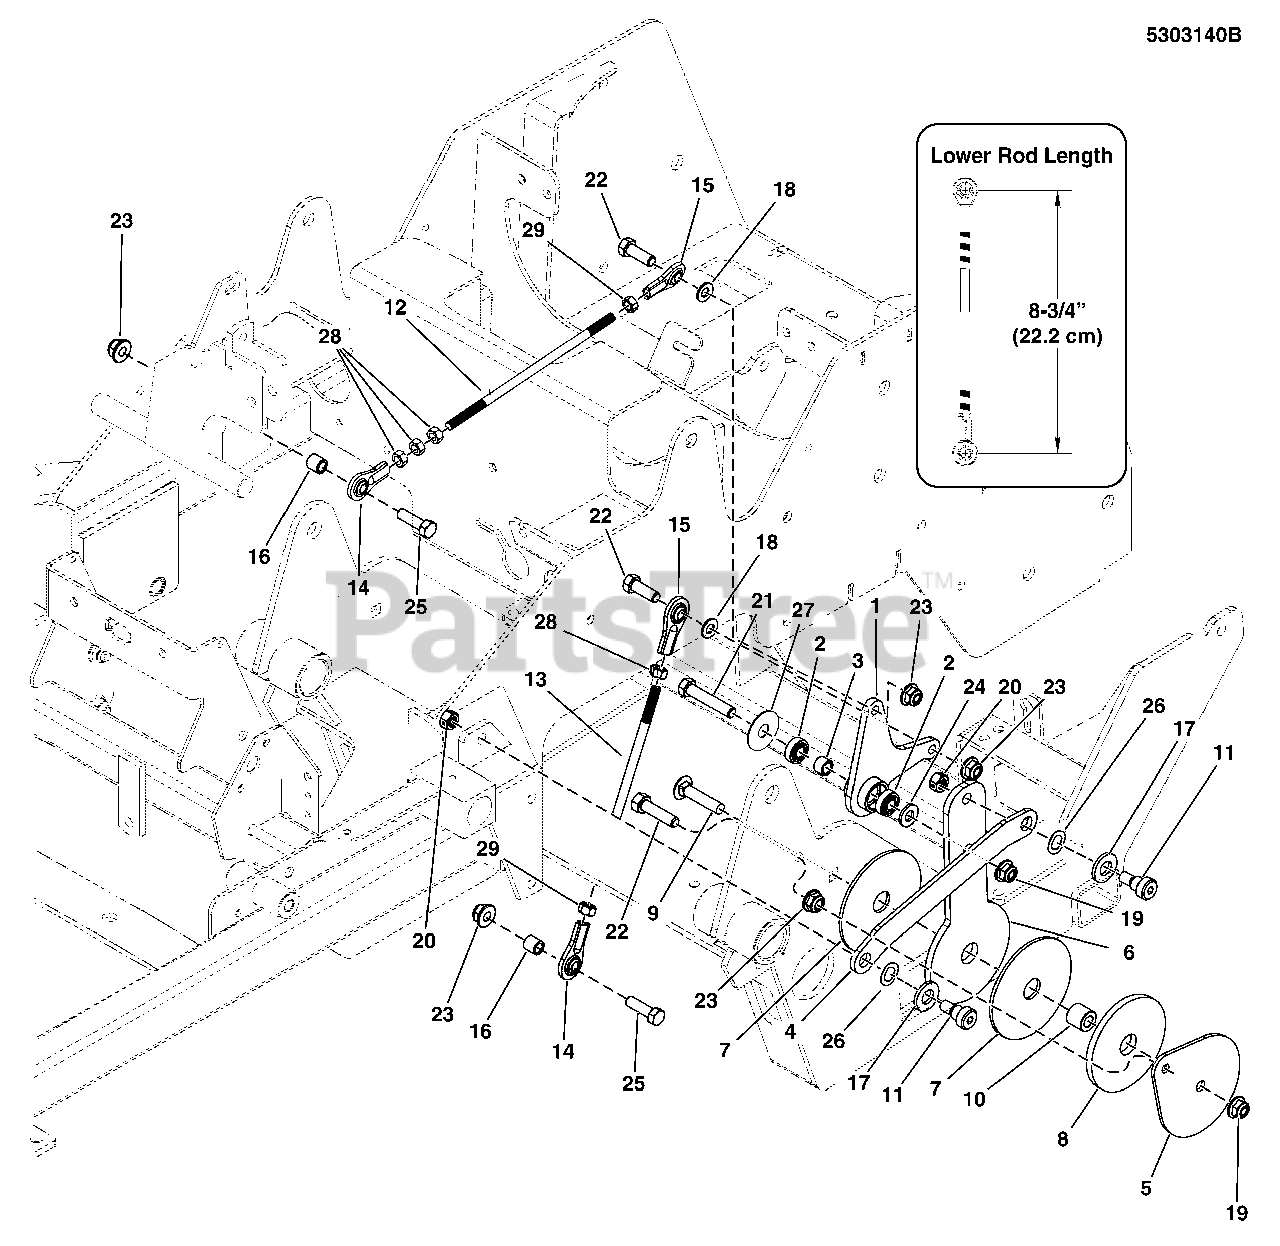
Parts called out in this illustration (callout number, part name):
1	PIVOT, CONTROL SYSTEM, S125XT
2	BEARING, .375" ID X .875" OD X .341" THK
3	SPACER, .39 X .55 X .38, PM, CZ
4	LINK, CONTROL SYSTEM ARM, IS600 - BLK
5	PLATE, CONTROL SYSTEM LOCK - BLK
6	PLATE, CONTROL SYSTEM ARM - HT
7	PAD, CONTROL SYSTEM
8	PAD, .77 X 3.50 X .25, POLYURETHANE
9	BOLT, 3/8-16 X 1-1/2, CARRIAGE, GD5, CZ
10	SPACER, .39 X .75 X .69, PM, CZ
11	BOLT, 3/8-16 X 3/8", 1/2" SHOULDER
12	ROD, 5/16 X 8.38, LH-RH, CZ
13	ROD, 5/16 X 7.00, LH-RH, CZ
14	BALL JOINT 5/16-24 RH FEMALE STAMPED STL
15	BALL JOINT 5/16-24 LH FEMALE STAMPED STL
16	SPACER, .33 X .50 X .50, YZ
17	WASHER, 1/2" GD9 YZ
18	WASHER, 5/16" SAE
19	NUT, 3/8 - 16 HEX NYLOCK FLANGE
20	NUT, Hex, Side Lock, 3/8-16
21	BOLT, 3/8-16 X 2, GD5, CZ
22	BOLT, 5/16-18 X 1-1/4" GD5 YZ
23	NUT, 5/16-18 HEX NYLOCK FLANGE NUT
24	WASHER, 3/8" GR. 9 FLAT
25	BOLT, 5/16-18 X 1-1/2" GD5 YZ
26	WAVE WASHER, 1/2"ID X 087"OD X .01 THK.
27	WASHER, 3/8" Fender
28	NUT, Hex, 5/16-24
29	NUT, 5/16-24 HEX, LH
